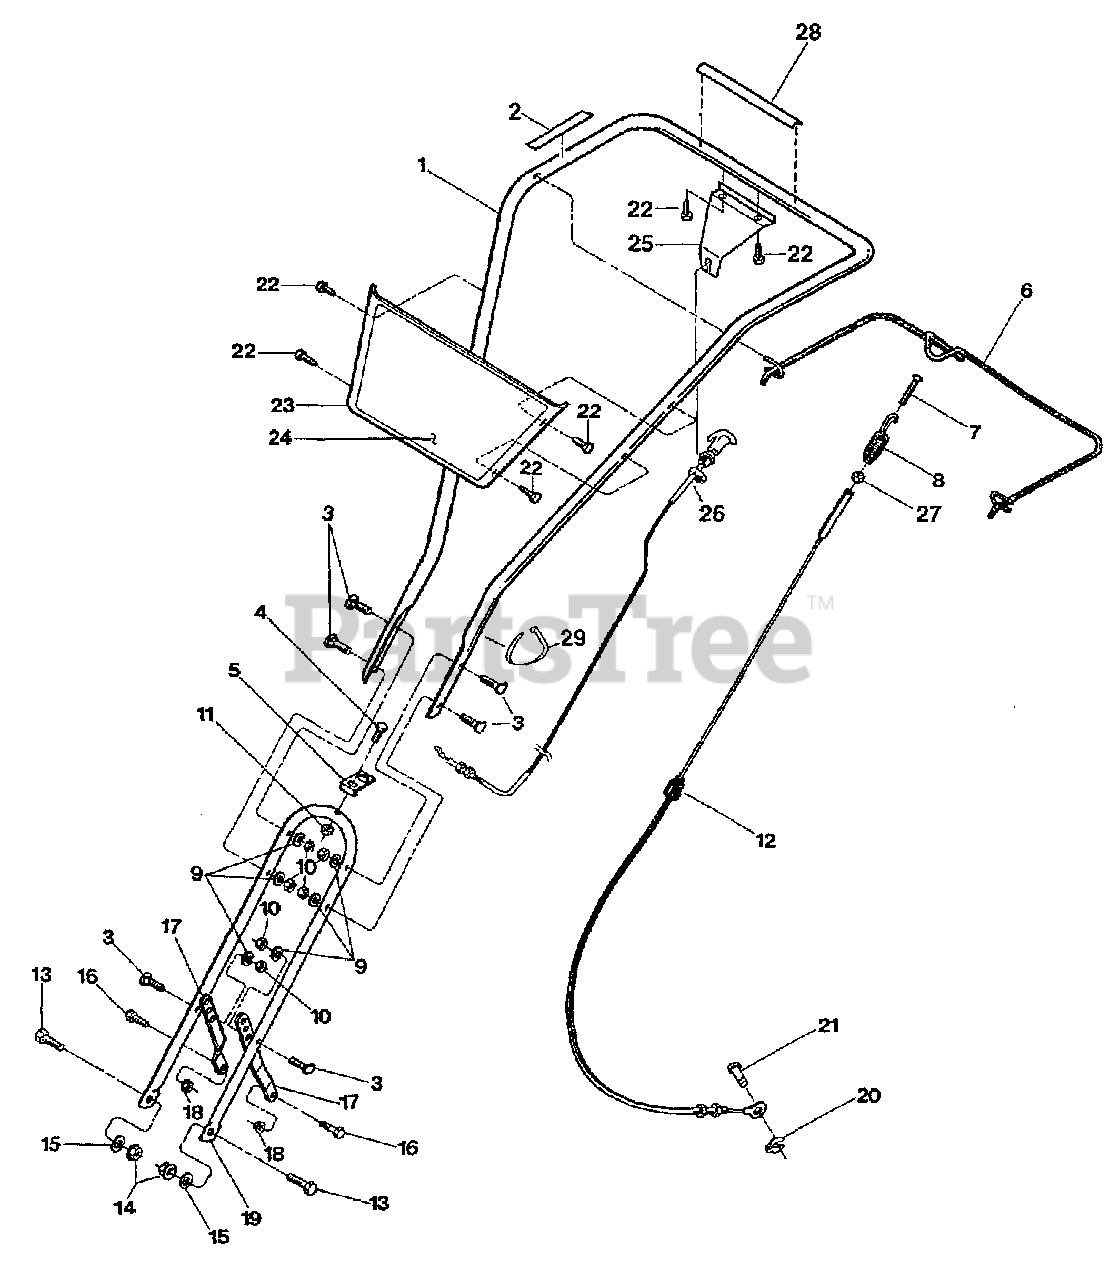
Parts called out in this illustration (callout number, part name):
1	Upper Handlebar
2	Decal, Forward Clutch Bail
3	Curved Hd. Screw, 5/16-18 x 1-1/2
4	Hex Hd. Screw, 1/4-20 x 1-1/4
5	Bracket, Forward Clutch Cable
6	Bail, Forward Clutch
7	Screw, #10-24 x 2
8	Spring, Forward Clutch
9	Lockwasher, 5/16
10	Hex Nut, 5/16-18
11	Hex Lock Nut, 1/4-20
12	Cable Assembly, Forward Clutch
13	Hex Hd. Screw, 3/8-16 x 3/4
14	Hex Lock Nut, 3/8-16
15	Flat Washer, 3/8
16	Hex Hd. Screw, 5/16-18 x 3/4
17	Handlebar Support
18	Hex Lock Nut, 5/16-18
19	Lower handlebar
20	Klip Ring
21	Clevis Pin
22	Hex Hd. Screw, 1/4-20 x 1/2, Self-Tapping.
24	Decal, Logo
25	Bracket, Reverse Clutch Cable
26	Cable Assembly, Reverse Clutch
27	Hex Nut, #10-24
28	Decal, Reverse Drive Control
29	Cable Tie
